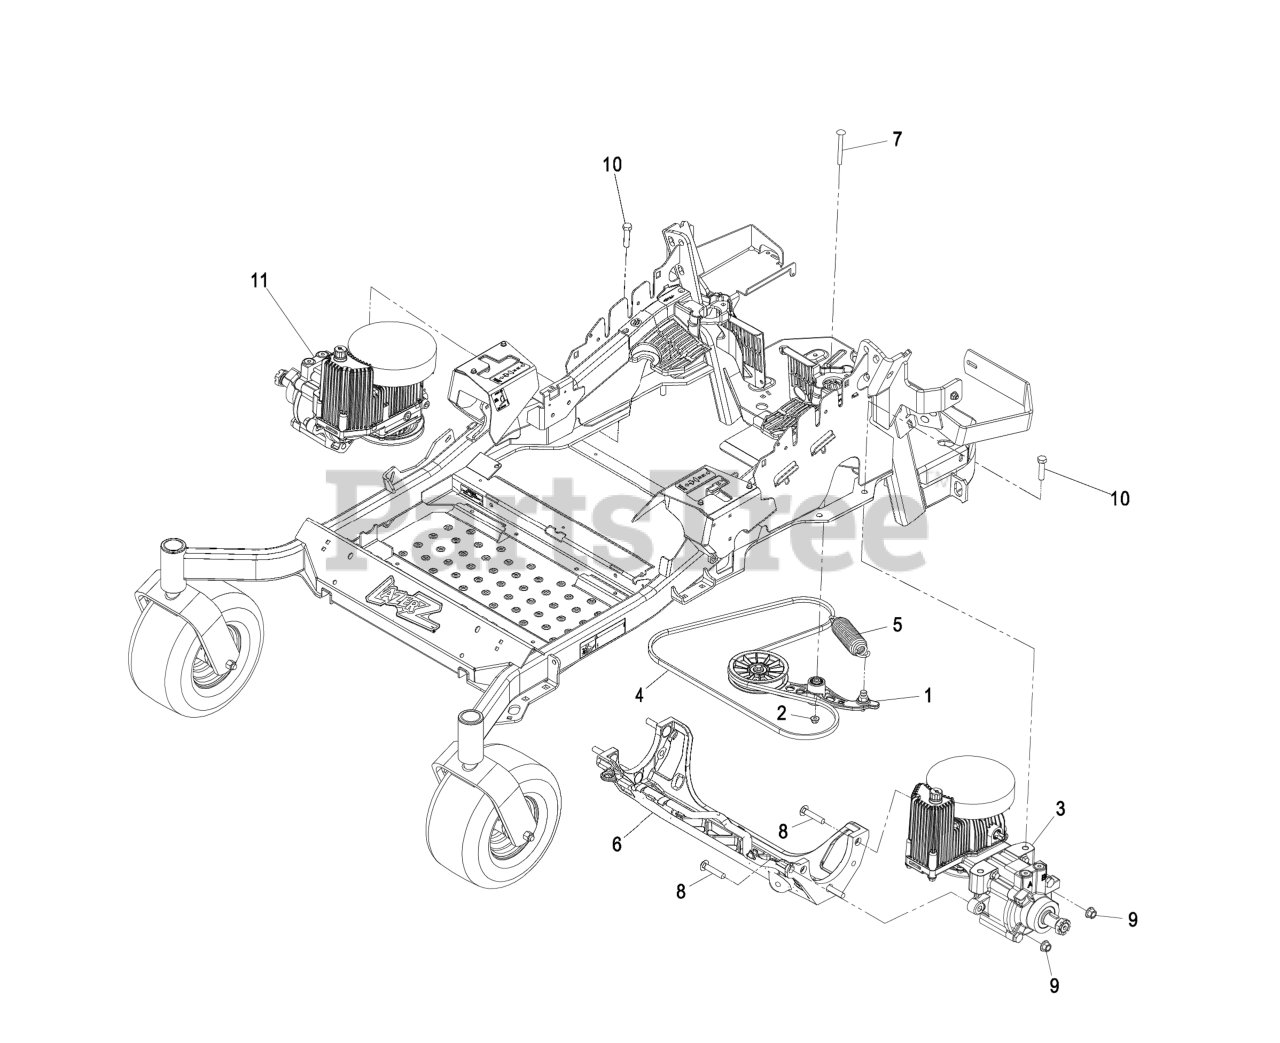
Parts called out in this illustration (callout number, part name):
2	Nut-Nyloc 3/8-16 Flg
4	BELT
7	BOLT-CARRIAGE
8	SCREW-CARR
9	Nut-Lock 1/2-13
10	SCREW-HH
